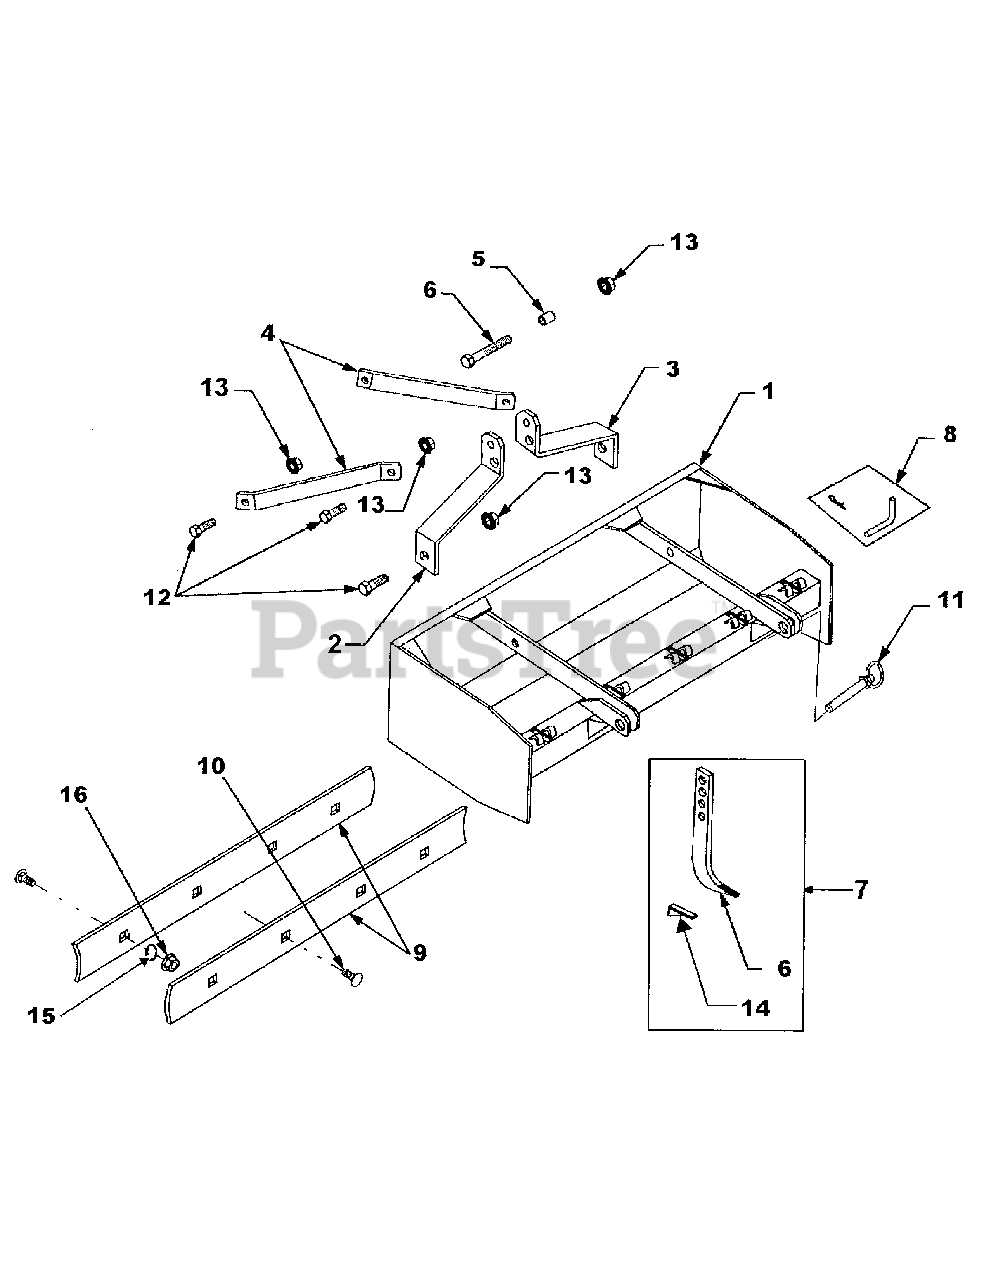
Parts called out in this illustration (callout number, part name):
1	Frame
2	Vertical Support Right
3	Vertical Support Left
4	Horizontal Support
5	Inner Spacer
6	Bolt, 3/4'' x 5''
6	Bolt, 3/4'' x 4''
7	Scarifier Shanks
8	Bent Pin w/ Cotter
9	Scraper Blade
10	Plow Bolt
11	Hitch Pins
12	Bolt, 3/4'' x 1 3/4''
12	Bolt, 3/4'' x 2 1/2''
13	Stover Nut, 3/4''
14	Scarifer Tooth
15	Lockwasher 5/8''
16	Hex Nut 5/8''
